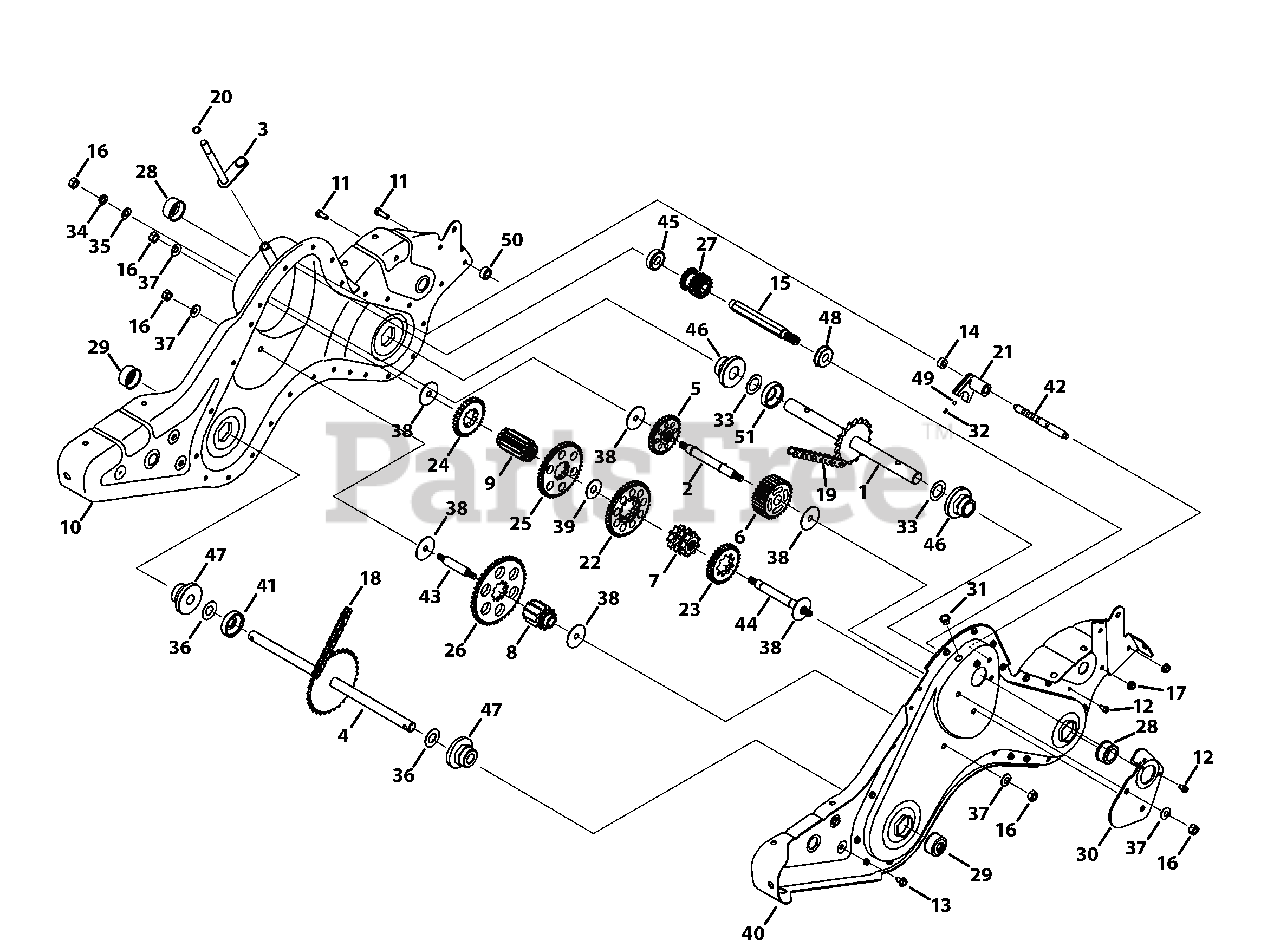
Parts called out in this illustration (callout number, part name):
1	Shaft Assembly, Tine, 18T
2	Shaft Assembly, Jack
3	Shaft Assembly, Shift Input
4	Shaft Assembly, Wheel, 33T
5	Gear Assembly, 30T Reverse Idler
6	Gear Assembly, 30T Tine Idler
7	Sprocket Assembly, 9T Tine Input
8	Sprocket Assembly, 10T Whl Input
9	Gear Assembly, 11T
10	RH Chain Case Housing Assembly
11	Hex Head Screw, 5/16-18 x 1.00
12	Screw, 1/4-20 x 0.625
13	Screw, :5/16-18 x 0.75
14	Spacer, .505 ID x .88 OD x .440
15	Input Shaft, .75
16	Nut, Hex, 7/16-20
17	Nut, Flangelock, 5/16-18
18	Endless Chain, #420 x 50 Links
19	Endless Chain, #50 x 54 Links
20	Snap Ring, .500
21	Clutch Collar
22	Gear Spur, 44T
23	Gear Spur, 30T
24	Gear Spur, 30T
25	Gear Spur, 44T
26	Gear Spur, 44T
27	Gear Spur, 16T
28	Shaft Seal, 1.0
29	Shaft Seal, .75
30	Positioner Gear Bracket
31	Tapered Cap Plug
32	Compression Spring, .230 OD
33	Washer, Flat, 1.03 x 1.62 x .03
34	Washer, Lock, 7/16
35	Washer, Flat,.474 x .879 x .064
36	Washer, Flat, .760 ID x 1.50 OD
37	Washer, Bell,.45 x 1.00 x .062
38	Washer, Thrust, .445 x 1.92 x .060
39	Washer, Flat,1.595 x .635 x .062
40	LH Chain Case Housing
41	Spacer, .75 x 2.0 x .50
42	Shaft Detent, .5 DIA
43	Shaft, Jack, .625 x 2.385
44	Shaft, Jack, .6250 x 5.0050
45	Ball Bearing, 17 x 40 x 12:6203
46	Flange Bearing, 1.0 x 2.5 x 1.38
47	Flange Bearing, .75 x 2.5 x 1.38
48	Ball Bearing, 17 x 40 x 12:6203
49	Ball, Detent, .250
50	Spacer, .315 x .750 x .375 LG
51	Spacer, 1.0 ID x 2.0 OD x.5 LG
